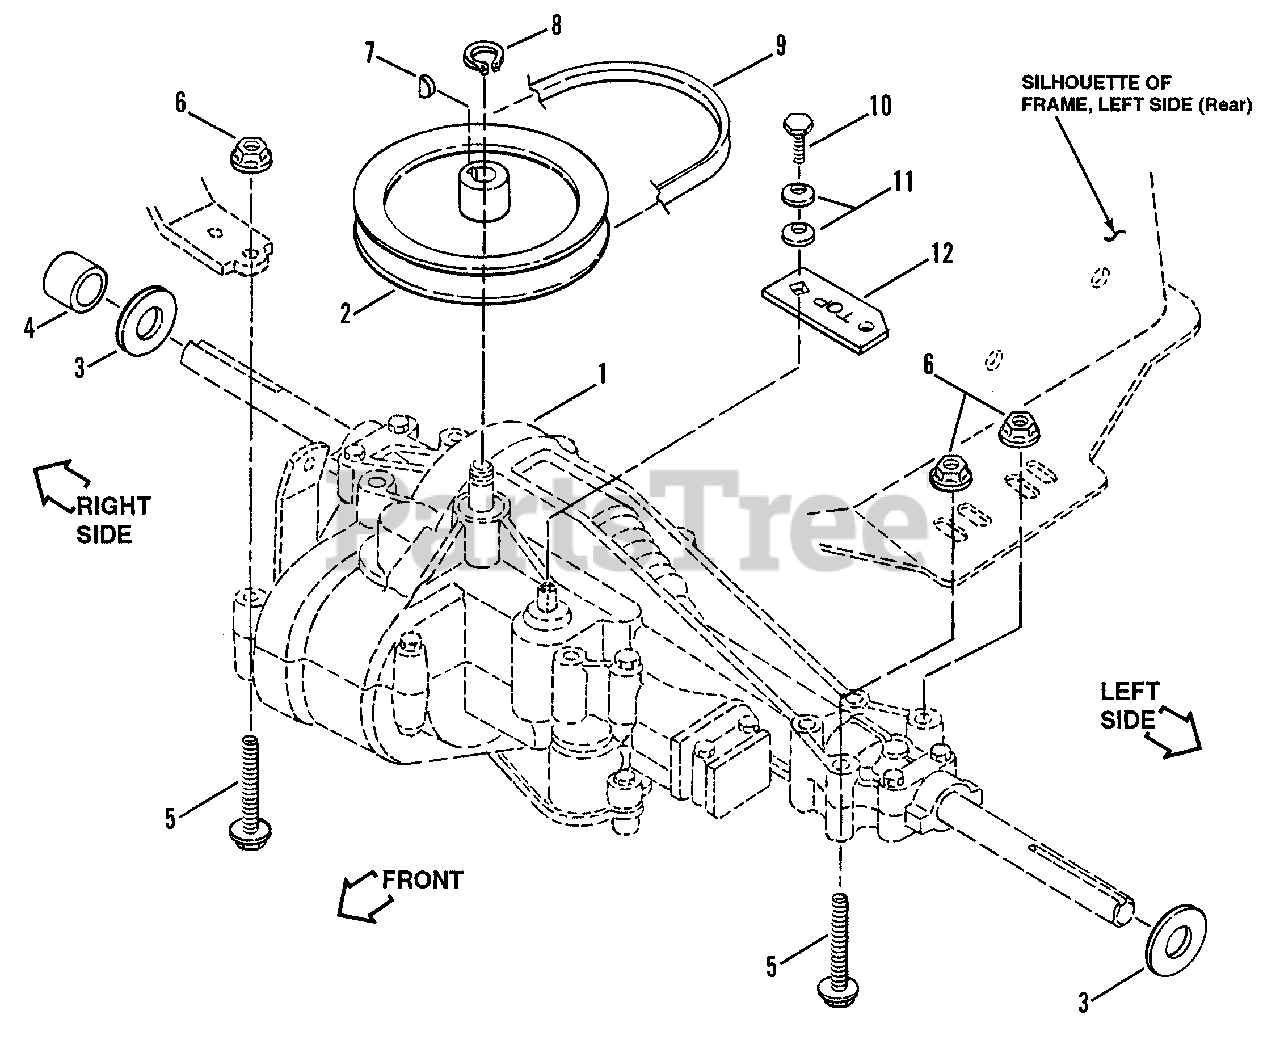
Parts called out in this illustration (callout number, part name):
1	TRANSAXLE, Peerless Model 915, 5-Speed (38" Model)
2	PULLEY, Drive
3	WASHER, Flat
5	BOLT, 5/16-18 x 2 1/4" Hex Flange Lock
6	NUT, 5/16-18 Hex Flange Lock
7	KEY, Woodruff
8	RING, Retaining
9	BELT, P915, Traction Drive, 97.08" EL
10	BOLT, 1/4-28 x 5/8" Hex Head, Grade 8
11	WASHER, Beliville
12	ARM, Shift Input
